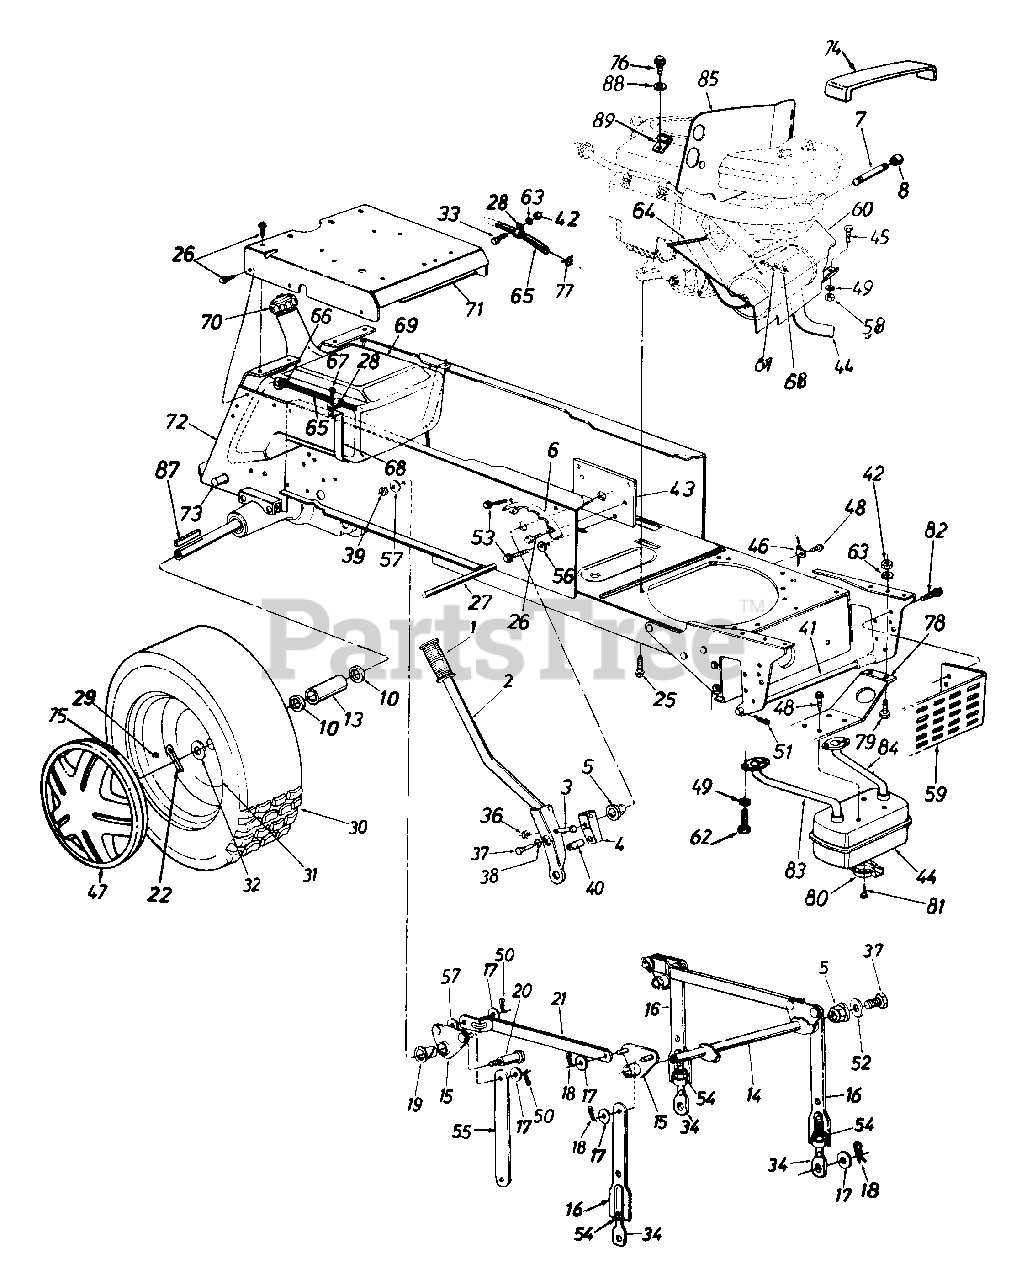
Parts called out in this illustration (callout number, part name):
1	Grip
2	Lift Handle Ass'y.
3	Hex Bolt 5/16-18 x 1.5" Lg.
4	Lift Shaft Drive
5	Plastic Hex Brg. 5/8" I.D.
8	Oil Drain Cap
10	Fl-Wash. 1.03" I.D. x 1.62" O.D.
13	Spacer 1" I.D. x 1.25" O.D.
14	Lift Shaft Ass'y.
15	Lift Pivot Brkt. Ass'y.
17	Fl-Wash. 1/2" I.D. x 1.00" O.D. x .090"
18	Hairpin Cotter
19	Nyliner 5/8" I.D. x .88" Lg.
20	Shld. Bolt 5/8" Dia. x .96" Lg. 3/8-16
25	Hex Wash. Hd. Scr. 3/8-16 x 1.25" Lg.
26	Hex Thd. Rolling Scr. 5/16-18 x .75" Lg.
27	Running Board Rod
28	Clamp
29	Air Valve
33	Hex Bolt 1/4-20 x .62" Lg.
34	Eye Bolt Adj. Link 1/2-13 Thd.
36	Hex Cent. L-Nut 5/16-18 Thd.
37	Hex Bolt 5/16-24 x .62" Lg.
39	Hex Top L-Nut 3/8-16 Thd.
40	Compression Spring
41	Deck Connecting Rod
42	Hex Nut 1/4-20 Thd.
45	Hex Bolt 5/16-18 x .75" Lg.
46	Mounting Clamp
47	Hub Cap
48	Hex Wash. Hd. TT-Tap Scr. 1/4-20 x .5" Lg.
49	L-Wash. 5/16" I.D.
50	Cotter Pin .09 Dia. x 1.0" Lg.
51	Int. Cotter Pin
52	Flat Wash. .34" I.D. x 1.12" O.D. x .125"
53	Hex Wash. Hd. AB-Tap Scr. 5/16-24 x .5" Lg.
54	Hex Nut 1/2-13 Thd.
56	Fl-Wash. .344" I.D.
57	Bell-Wash. .4" I.D. x 1.13" O.D.
58	Hex Nut 5/16-18 Thd.
59	Heat Shield
60	Front Heat Shield
61	Spec. L-Wash. 5/16" I.D.
62	Cap Scr. 5/16-18 x 1" Lg.
63	L-Wash. 1/4" I.D.
64	Trim Strip 12" Lg.
65	Fuel Line 46" Lg.
66	Hose Clamp
67	Hex AB-Tap Scr. 1/4 x .62" Lg.
68	Fuel Tank Strap
69	Gas Tank
70	Gas Gauge
74	Heat Baffle Seal
75	Spring Clip
76	Truss Mach. B-Tap Scr. #10 x .5" Lg.
77	Hose Clamp
78	Muffler Mounting Brkt.
79	Hex Bolt 1/4-20 x .62" Lg.
80	Muffler Deflector
81	Hex Wash. Hd. F-Tap Scr. #8 x .32" Lg
82	Hex Wash. Hd. TT-Tap Scr. 5/16" - 18 x .62" Lg.
83	Exhaust Tube - R.H.
84	Exhaust Tube - L.H.
85	Top Heat Shield
87	Sq. Key 1/4" x 3" Lg.
88	Fl-Wash. .188" I.D. x .438" O.D.
89	Clamp
